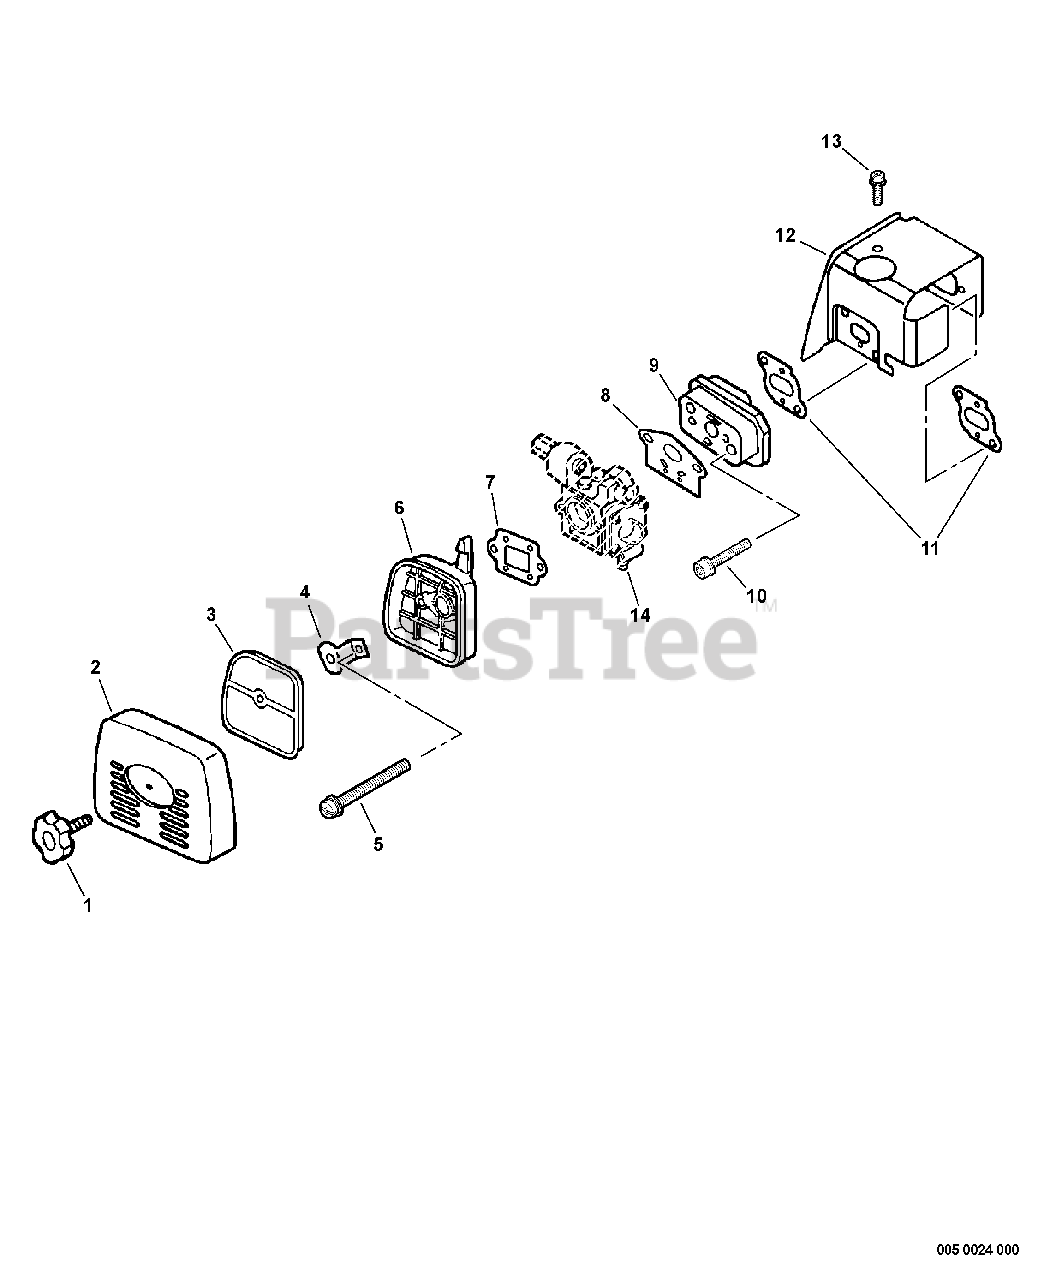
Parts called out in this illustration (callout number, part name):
1	THUMBSCREW
2	COVER, AIR FILTER
3	FILTER, HEAVY-DUTY AIR
4	PLATE, PREVENT
5	SCREW 5×60
6	CASE, AIR FILTER
8	GASKET, CARBURETOR
9	INSULATOR, INTAKE
10	BOLT 5×25
11	GASKET, INTAKE
12	COVER, CYLINDER
14	CARBURETOR
15	TUNE-UP KIT
16	TUNE-UP KIT
